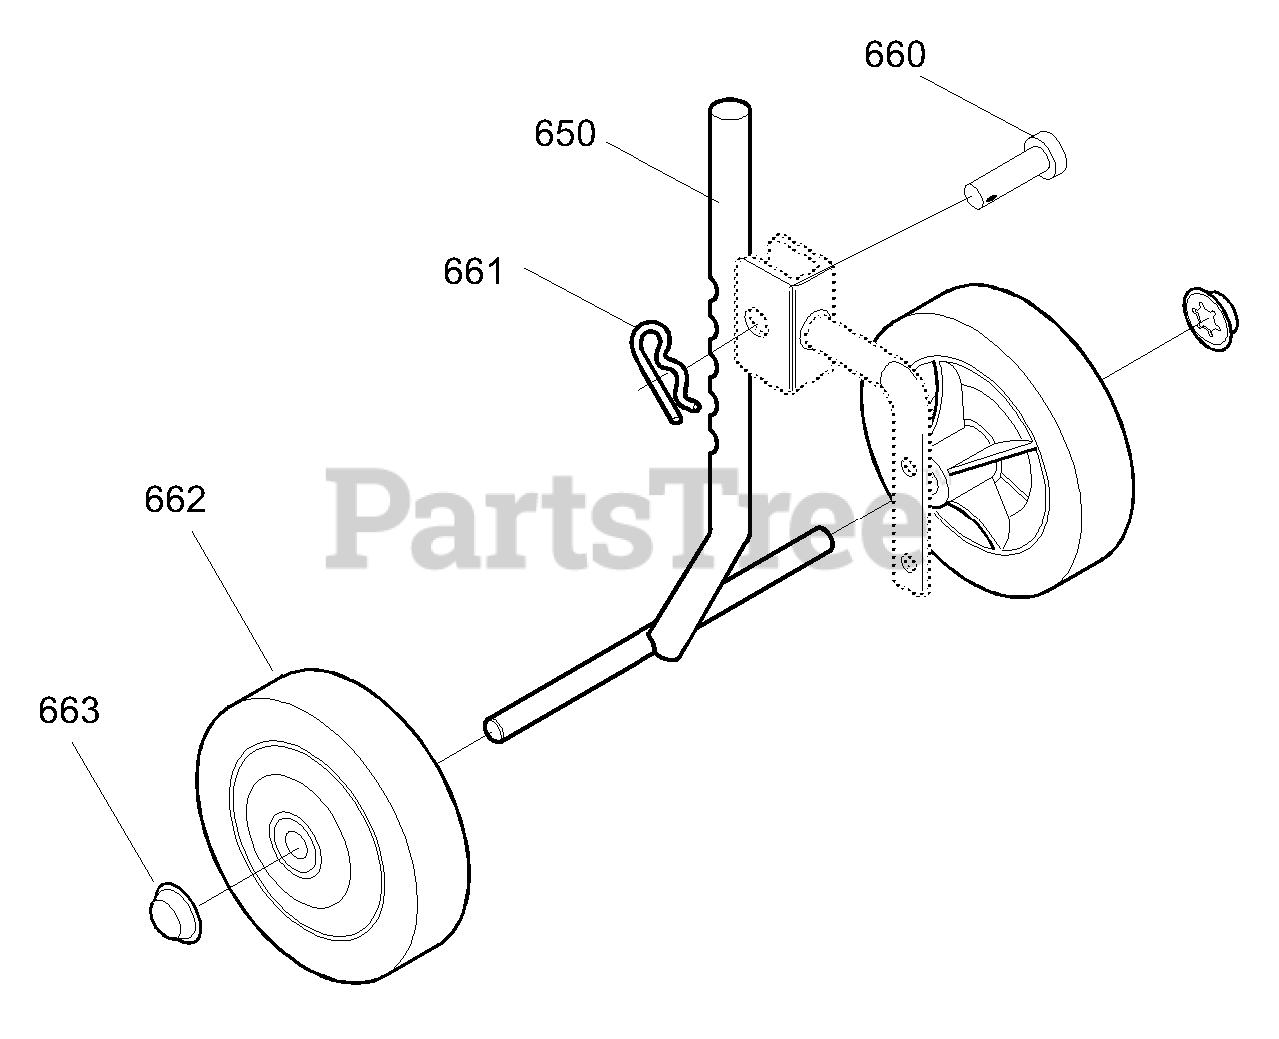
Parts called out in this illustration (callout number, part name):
650	Wheel Support Assy.
660	Clevis Pin
661	Hair Pin
662	Tire & Rim
663	Push On Nut
